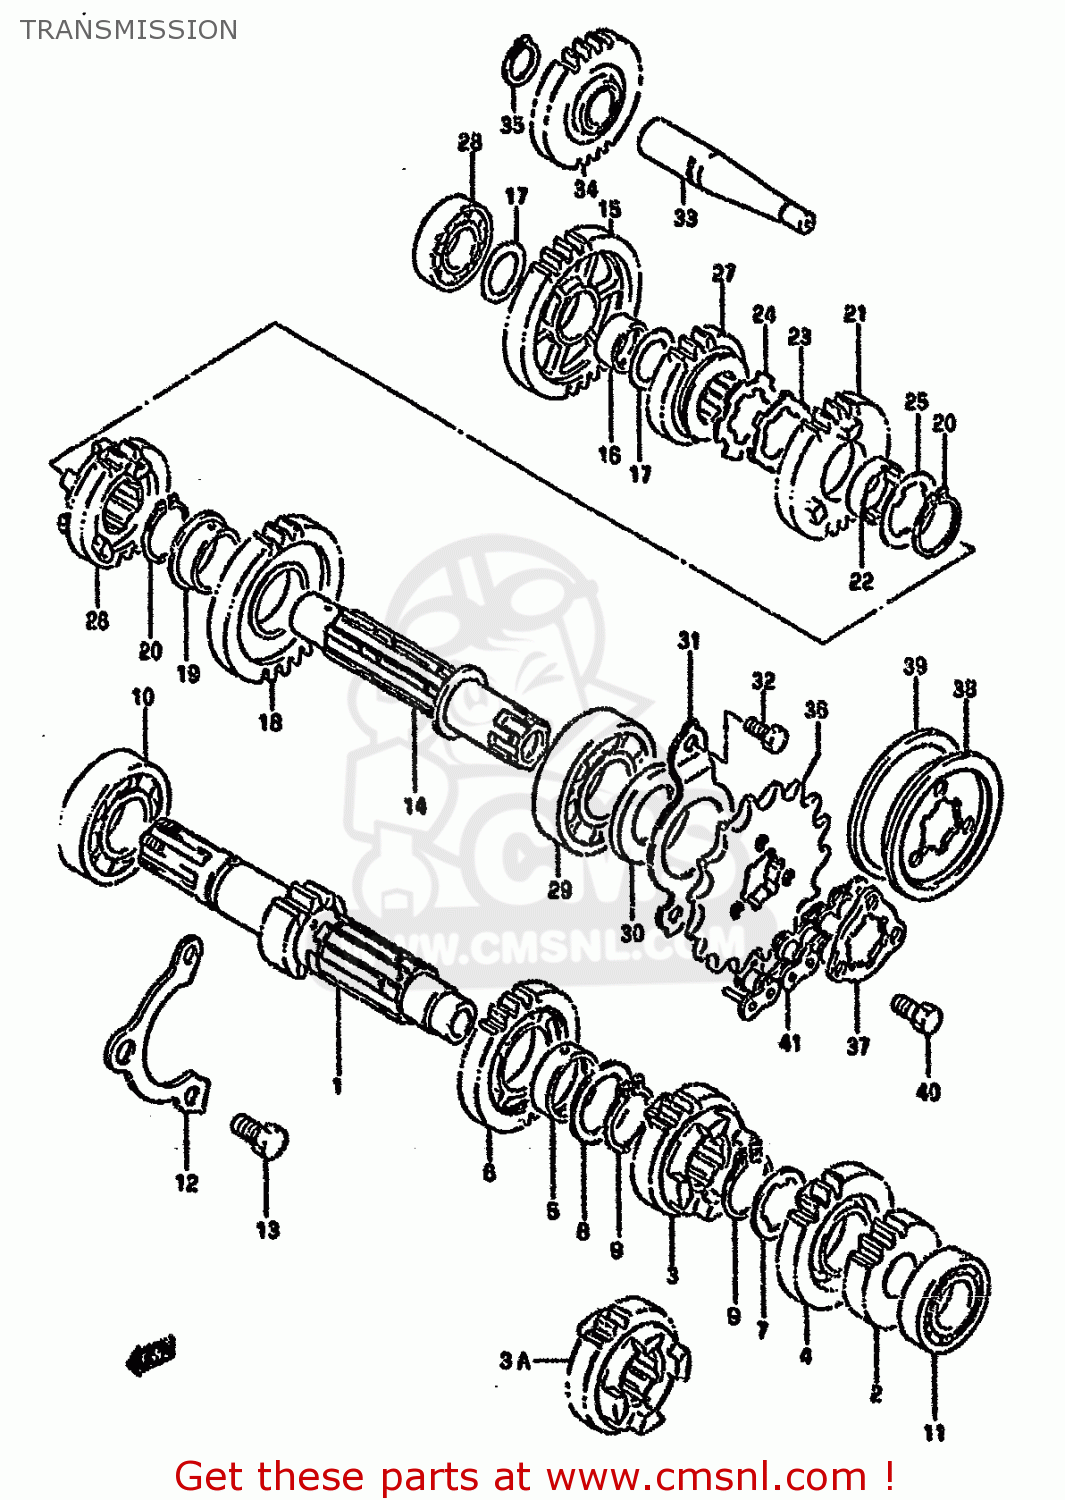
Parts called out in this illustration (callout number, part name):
1	SHAFT,COUNTER
2	GEAR,2ND DRIVE
3	GEAR,3RD DRIVE
3A	GEAR,THIRD DRIVE
4	GEAR,FOURTH DRIVE
5	BUSHING 25X29X10
6	GEAR,5TH DRIVE
7	WASHER,LOCK
8	WASHER
9	RING,SNAP
10	BEARING(22X56X16)
11	BEARING
12	RETAINER,CNTR SHAFT BEARING
13	BOLT
14	SHAFT,DRIVE
15	GEAR,1ST DRIVEN
16	BUSH(20X24X13)
17	WASHER
18	GEAR,2ND DRIVEN
19	BUSH
20	RING,SNAP
21	GEAR,3RD DRIVEN
22	BUSHING
23	WASHER
24	WASHER,LOCK
25	WASHER,LOCK
26	GEAR,FOURTH DRIVEN
27	GEAR,FIFTH DRIVEN
28	BEARING(20X42X12)
29	BEARING(25X62X17)
30	SEAL,OIL(25X45X5)
31	RETAINER,DRIVE SHAFT OIL SEAL
32	BOLT
33	SHAFT,KICK STARTER IDLE
34	GEAR,KICK STARTER IDLE
35	CIRCLIP
36	SPROCKET,ENGINE(NT:16)
37	PLATE,ENGINE SPROCKET
38	PLATE,ENGINE SPROCKET
39	DAMPER,ENGIN SPROCKET
40	BOLT
41	CHAIN(DID520V,114L)
